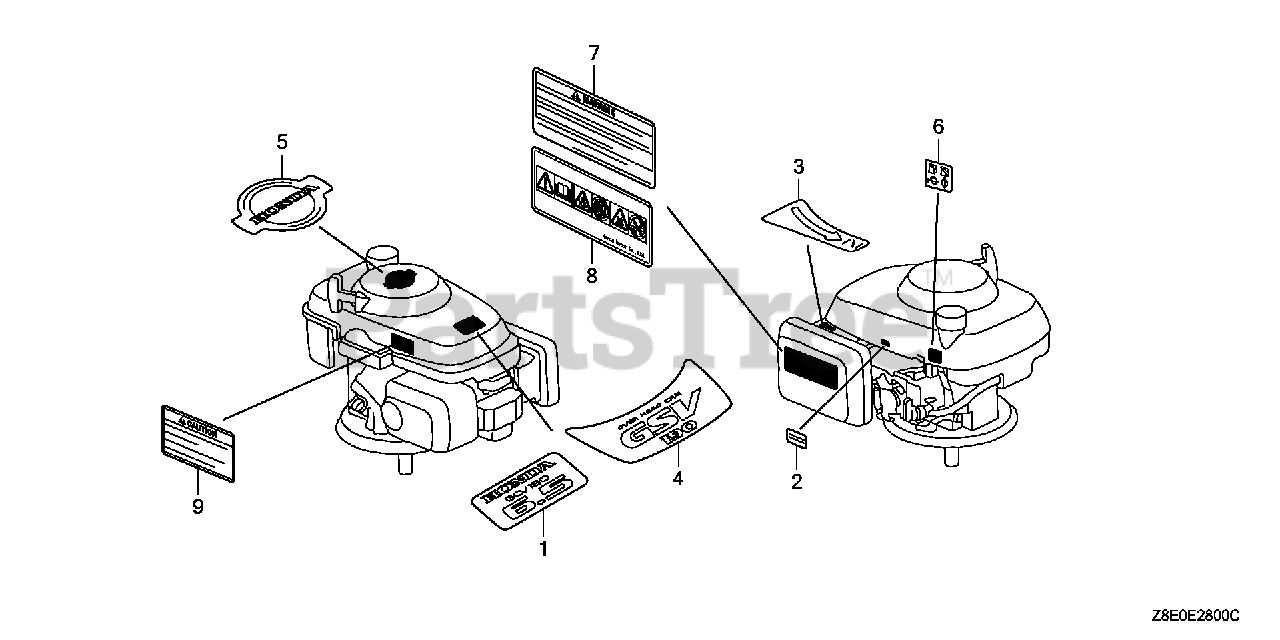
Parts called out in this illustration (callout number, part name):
1	MARK, EMBLEM (GSV190 6.5)
2	LABEL, WARNING (NOT CERTIFIED FOR SALE)
3	MARK, CHOKE INDICATION
6	MARK, FUEL PETCOCK CAUTION
7	MARK, OPERATOR CAUTION (ENGLISH)
